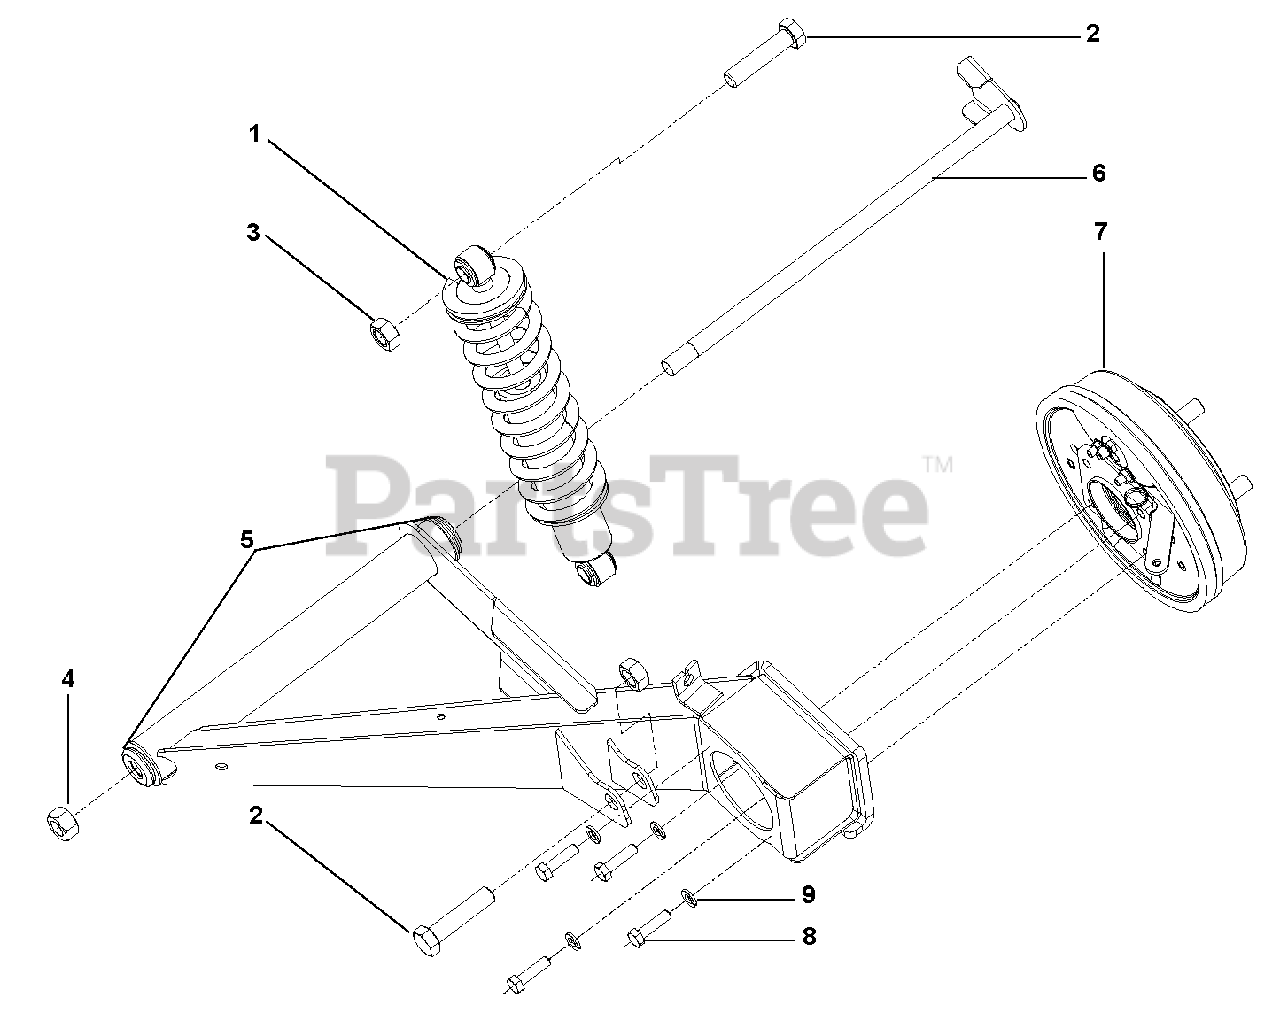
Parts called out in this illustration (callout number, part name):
1	SHOCK COIL REAR TRUCK
2	HHCS M14X2.00X60 GR8.8
3	NUT HEX NYLOCK M14X2.00
4	NUT-LK-TOP .563-12 GR5 YWZC
5	BUSHING IDLER ARM RUBBER
6	CENTER PIVOT TUBE WELDMENT
7	RH DRUM ASM 180MM 4 ON 4" BC
8	HHCS M8X1.25X30 GR10.9 YLW PLT
9	WSHR-LK M8 YWZC
